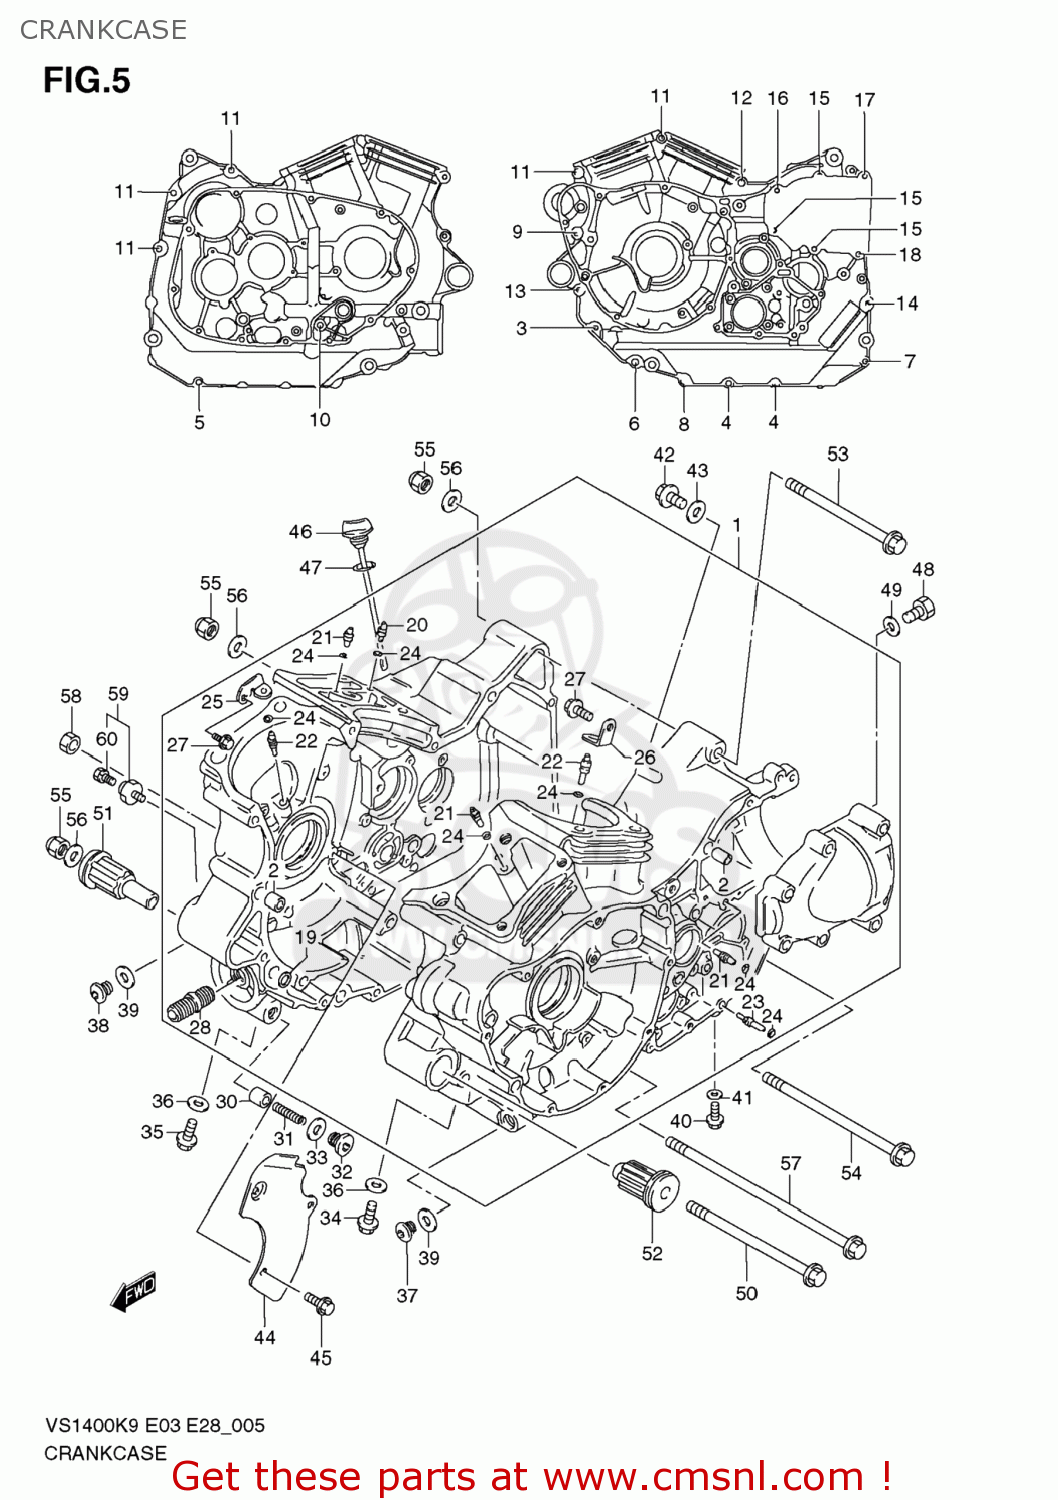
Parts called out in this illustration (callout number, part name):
1	CRANKCASE SET
2	PIN(8.4X11X20)
3	BOLT
4	BOLT
5	BOLT
6	BOLT
7	BOLT
8	BOLT(8X70)
9	BOLT
10	BOLT(8X115)
11	BOLT(8X95)
12	BOLT(8X50)
13	BOLT(8X70)
14	BOLT(8X80)
15	BOLT
16	BOLT
17	BOLT
18	BOLT
19	O RING(D:1.9,ID:12.6)
20	JET(2.2)
21	JET,AIR(14)
22	JET,PISTON COOLING(0.8)
23	JET,MISSION OIL(1.4)
24	O RING(D:1.2,ID:4)
25	PLATE,PISTON JET FR
26	PLATE,PISTON JET RR
27	BOLT(6X12)
28	UNION,OIL STAND
29	PLATE,CRANK THRUST
30	PLUNGER,OIL CONTROLL
31	SPRING
32	PLUG,16X8
33	GASKET(16X22X2) (NAS)
34	BOLT
35	BOLT
36	GASKET(8.2X14X1) (NAS)
37	PLUG,14X12
38	PLUG
39	GASKET(13.8X18.8X4.8) (NAS)
40	BOLT
41	GASKET(5.8X13X1.2) (NAS)
42	PLUG(12X10)
43	GASKET(12.1X16.2X3.7) (NAS)
44	PLATE,OIL SEPARATOR
45	BOLT(6X12)
46	GAUGE,OIL LEVEL
47	O RING(D:3.1,ID:16.8)
48	PLUG(12X20)
49	GASKET(12.1X16.2X3.7) (NAS)
50	BOLT(10X155)
51	BUSH,ENGINE MOUNTING,R
52	BUSH,ENGINE MOUNTING
53	BOLT(10X135)
54	BOLT(10X180)
55	NUT
56	WASHER
57	BOLT(10X225)
58	NUT
59	SWITCH ASSY,OIL PRESSURE
60	BOLT,OIL PRESSURE SWITCH
